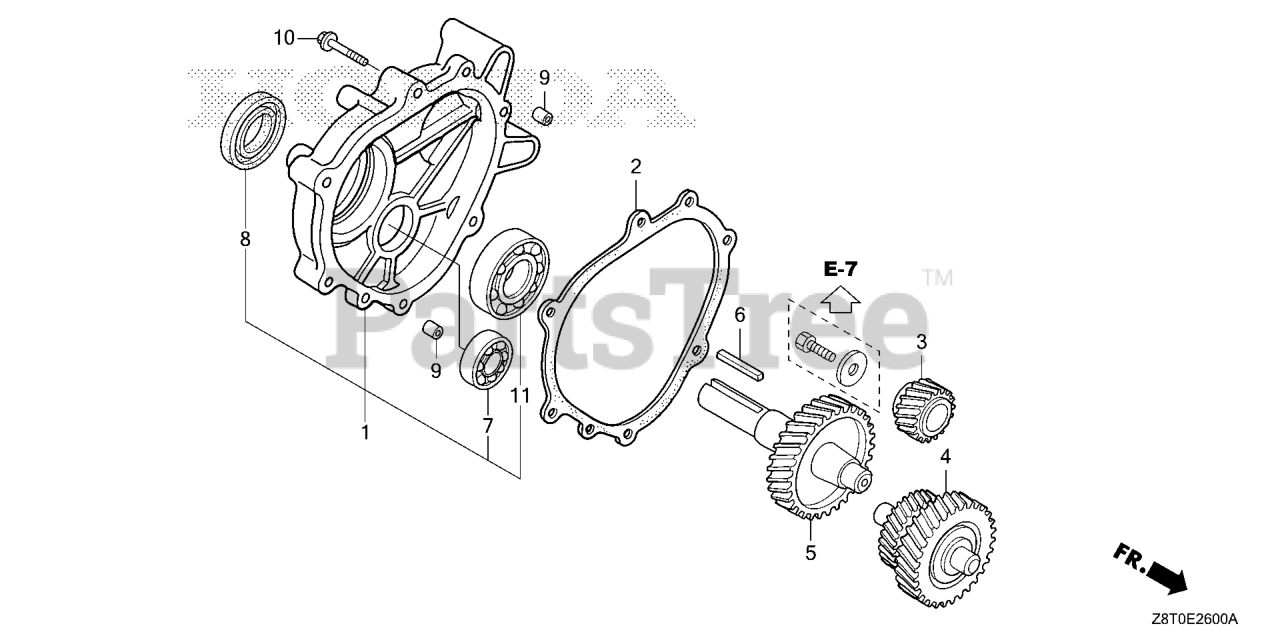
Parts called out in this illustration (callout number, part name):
1	COVER ASSY., GEAR CASE
2	GASKET, CHAIN CASE COVER
3	GEAR, PRIMARY DRIVE
4	COUNTERSHAFT
5	SHAFT, P.T.O. (L-TYPE)
6	KEY (7X7X33)
7	BEARING, RADIAL BALL (6202)
8	OIL SEAL (30X46X8) (NOK ASIA)
9	PIN A, DOWEL (8X14)
10	BOLT, FLANGE (8X40) Use up to Engine SN 1003236.
11	BEARING, RADIAL BALL (6206)
